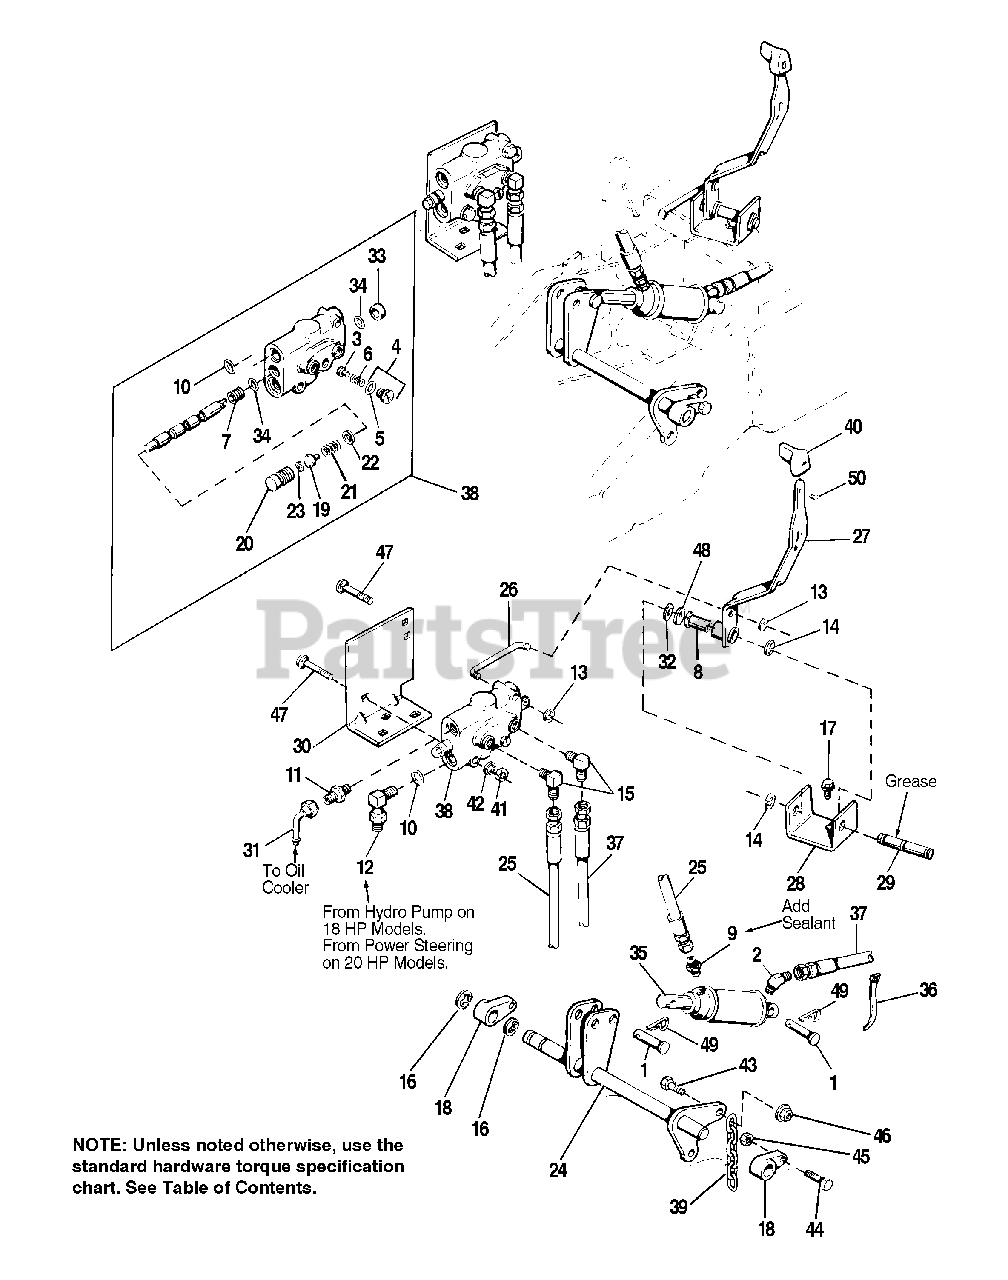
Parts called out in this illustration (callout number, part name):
1	PIN, Yoke, 5/8 x 2-1/16
2	FITTING, Elbow 45°, 1/8-27 x 1/2-70
3	PLUNGER, Lift Check
4	PLUG & O-RING ASSY.
5	"O" RING
8	BUSHING, Nylon, 41/64" I.D. x 49/64" O.D. x 1-1/2"
9	FITTING, Hydraulic
11	FITTING, Hydraulic
12	FITTING, Hydraulic
13	RING, Retaining, "E" Type, 3/16
14	RING, Retaining, "E" Type, 5/8
15	FITTING, Hydraulic
16	"E" RING, External
17	SCREW, Taptite, 5/16-18 x 3/4
18	BEARING, Lift Shaft
20	CAP, Valve Assy.
23	RING, Retaining
24	LIFT ASSY., Cylinder
25	HOSE ASSY., Hyd.
26	ROD, Control
27	CONTROL LEVER ASSY.
28	BRACKET, Support
29	SHAFT, Control Support
30	PLATE, Valve Mount
31	FITTING, Hydraulic
32	WASHER, Spring
33	WIPER, Scraper
34	"O" RING
35	CYLINDER, Hyd., Lift
36	TIE, Plastic
37	HOSE ASSY., Hyd.
38	VALVE ASSY., Control
39	CHAIN, Lift
40	KNOB, Control Handle
41	NUT, Hex, 1/4-20
42	LOCKWASHER, 1/4
43	CAPSCREW, 3/8-16 x 1.0
44	CAPSCREW, Hex Hd., 5/16-18 x 1-1/4
45	LOCKNUT, Hex, 5/16-18
46	NUT, Hex, Flange, 3/8-16
47	CARRIAGE BOLT, 1/4-20 x 2
48	WASHER, Plain, 21/32 I.D. x 1-1/4 O.D. x 1/16
49	CLIP, Hairpin
50	SCREW, Plastite, 1/4 x 1
